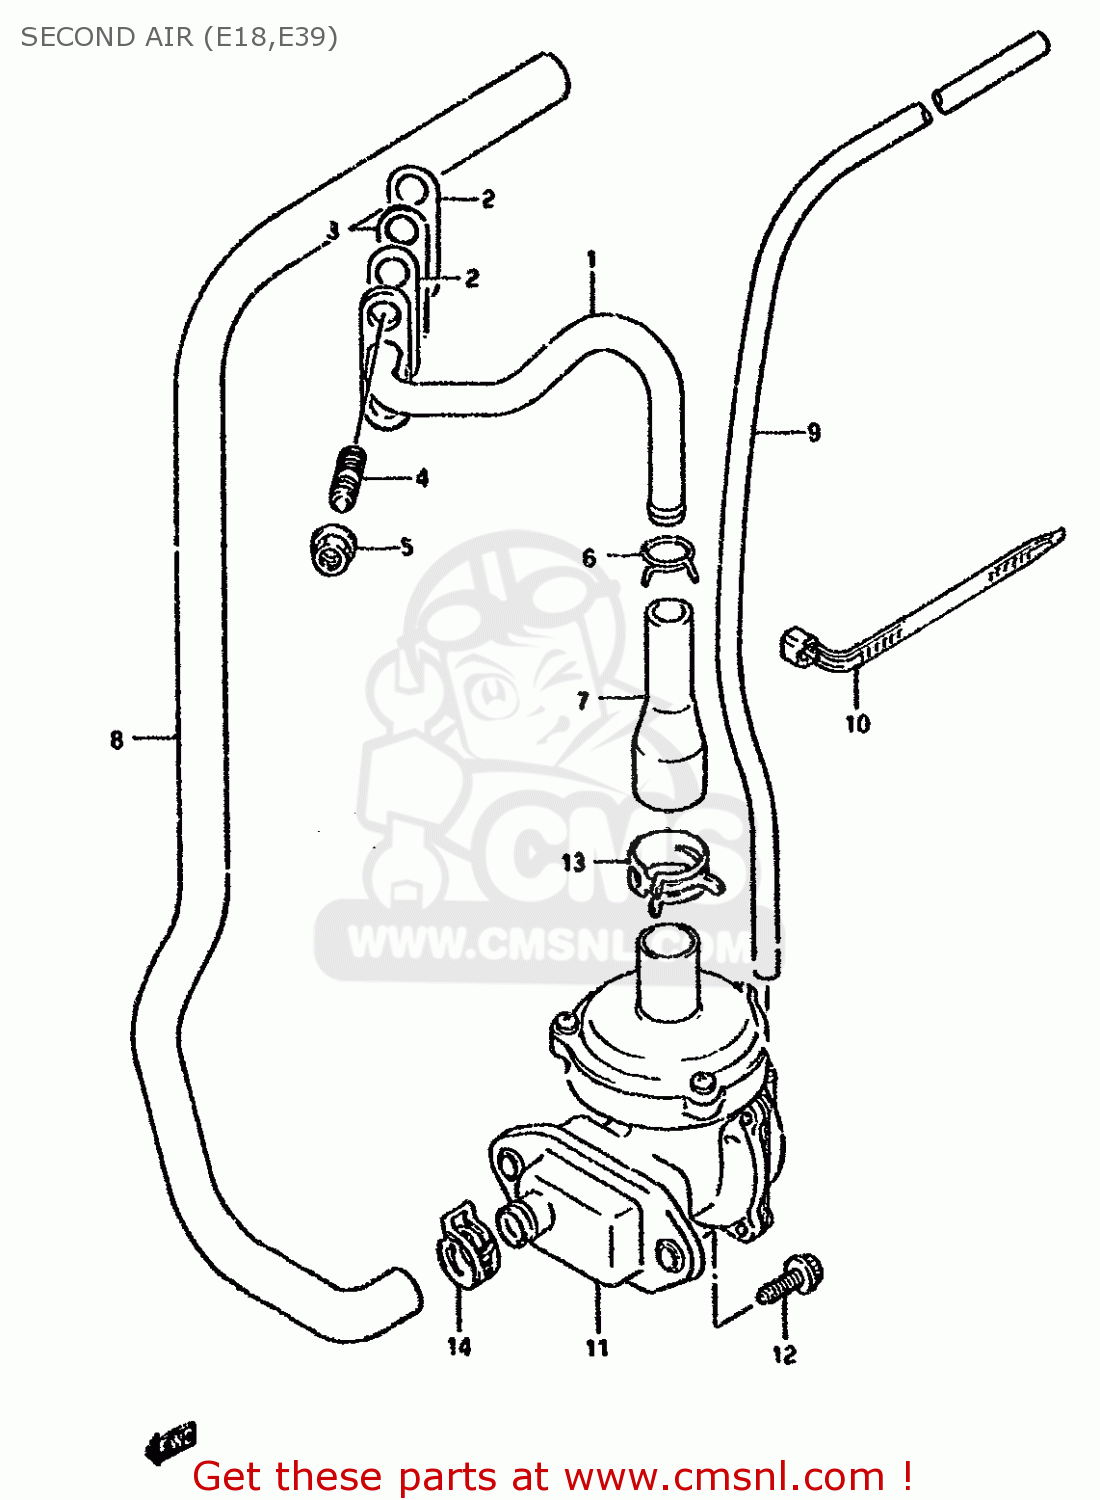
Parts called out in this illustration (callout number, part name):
1	PIPE,2ND AIR
2	GASKET (NA)
3	PLATE
4	BOLT
5	NUT
6	CLIP
7	HOSE, 2ND AIR
8	HOSE, 2ND AIR NO.4
9	HOSE(4X7X600)
10	CLAMP L:165
11	VALVE ASSY, 2ND AIR REED
12	BOLT MAGNETO S
13	CLIP
14	CLIP
